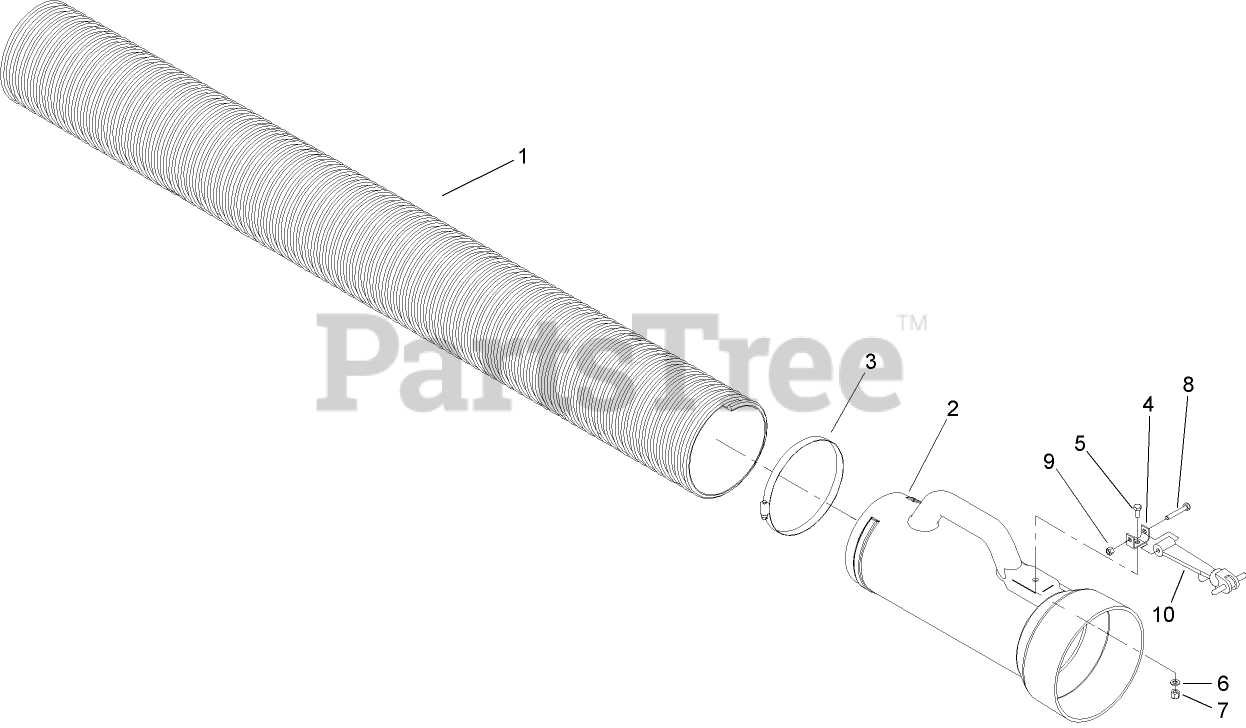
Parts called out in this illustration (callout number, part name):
1	HOSE-FLEXIBLE
2	TUBE-HANDLE
3	CLAMP
4	BRACKET-ANCHOR
5	SCREW-HH
6	WASHER-PLAIN
7	NUT-LOCK, NI
8	SCREW-HH
9	NUT-LOCK, NI
10	HOLDDOWN-HOOD
